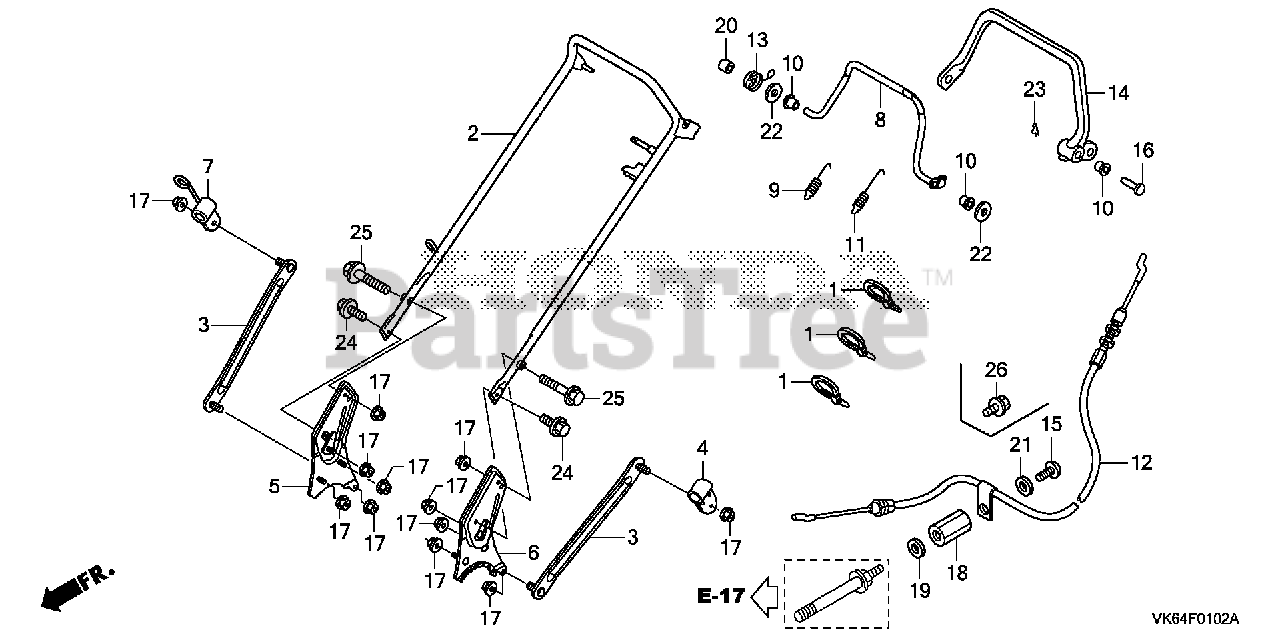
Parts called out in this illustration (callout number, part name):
1	TIE, CABLE
2	PIPE, HANDLE *NH105* (MAT BLACK)
3	PLATE, HANDLE SUPPORT
4	HANGER, HANDLE SUPPORT
5	STAY, R. HANDLE
6	STAY, L. HANDLE
8	LEVER, CLUTCH
9	SPRING, CLUTCH
10	BUSH, CLUTCH LEVER
11	SPRING, CLUTCH LEVER RETURN
12	CABLE, BRAKE
13	SPRING, R. STOP RETURN
14	LEVER, BRAKE *NH105* (MAT BLACK)
16	PIN, CLUTCH LEVER
17	NUT, FLANGE (8MM)
18	NUT, COUPLING (6X18)
19	WASHER (6MM)
20	COLLAR (8X11X13.5)
22	WASHER, PLAIN (8MM)
23	PIN, LOCK (8MM)
24	BOLT, FLANGE (8X16) Use from Engine SN 1000016.
25	BOLT, FLANGE (8X40) Use up to Engine SN 1003236.
26	BOLT, FLANGE (6X10)
